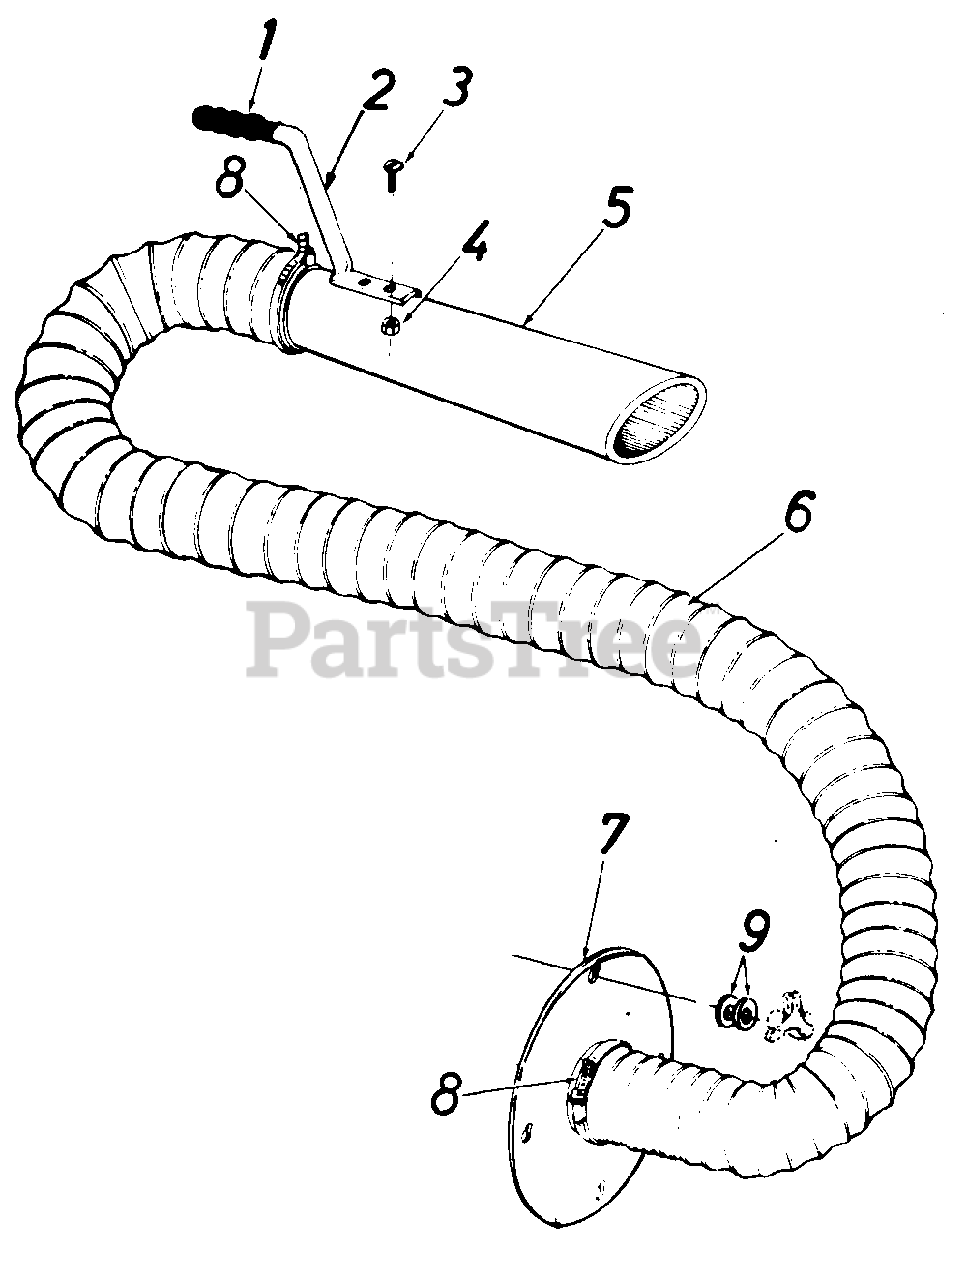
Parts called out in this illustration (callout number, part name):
1	Handle Grip
2	Handle
3	Truss Sems Scr. 10-24 x 1/2" Lg.*
4	Hex Nut 10-24 Thd.
5	Hose Nozzle
6	Flexible Hose 4" Dia. x 10' Lg.
9	Flat Washer .34 I.D. x 1.12 O.D.
